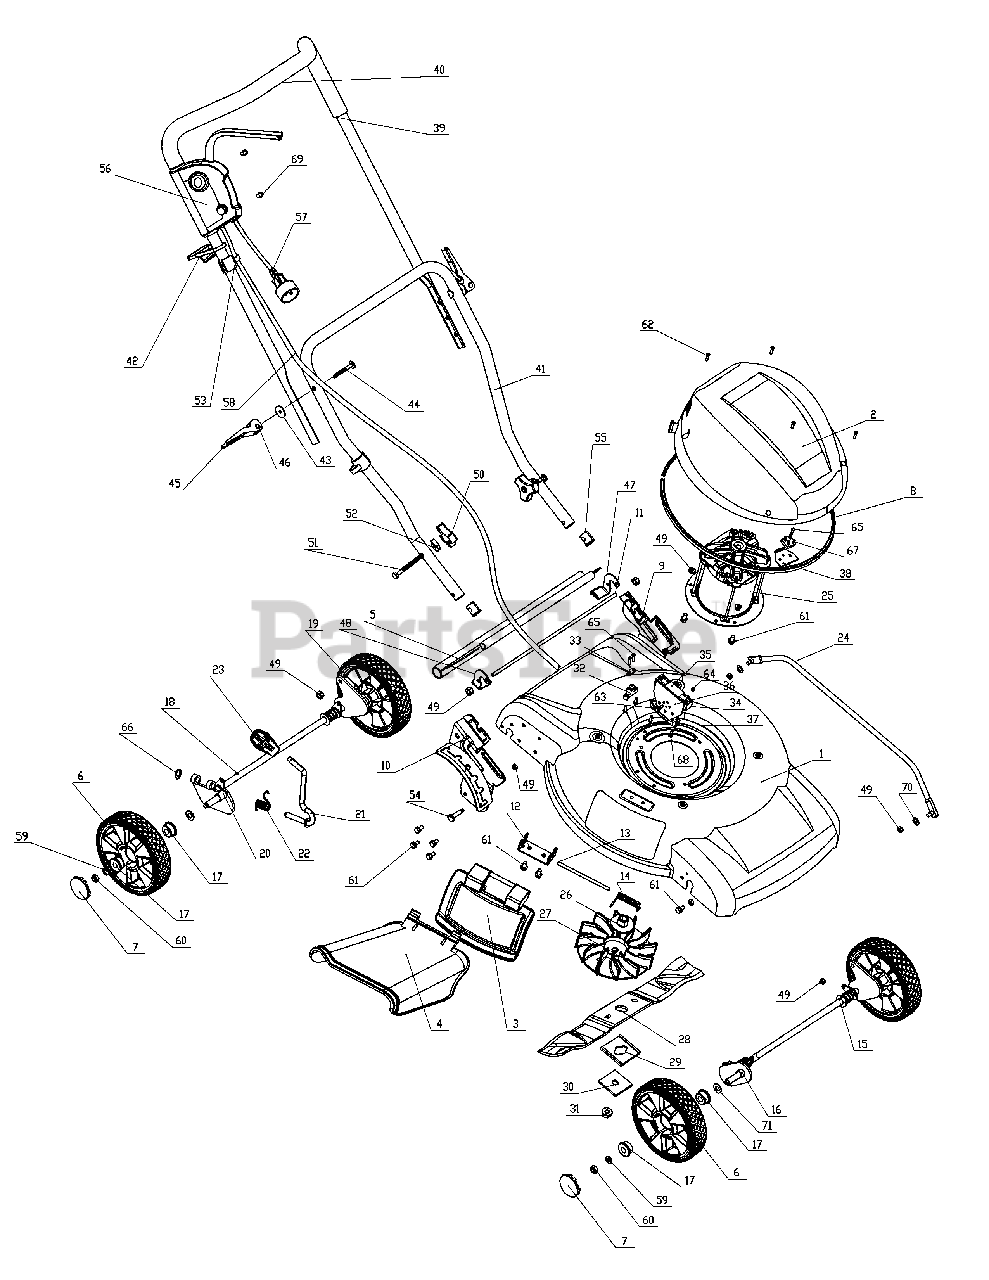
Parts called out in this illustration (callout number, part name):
1	Deck, 19", 3-In-1
2	Shroud
3	Door, Discharge
4	Chute, Discharge
5	Trailshield
6	Wheel, Front
7	Cap, Wheel
8	Seal, Shroud
9	Bracket, Wheel, Left
10	Bracket, Wheel, Right
11	Rod, Trailshield
12	Bracket, Deflector, Chute
13	Rod, Door, Chute
14	Spring, Door, Discharge
15	Axle, Assembly, Front
16	Washer
17	Bush, Wheel
18	Axle, Assembly, Rear
19	Washer
20	Washer
21	Lever, Spring
22	Spring, Lever
23	Knob, Adjustment, Height
24	Link, Height, Adjustment
25	Motor
26	Adapter, Blade
27	Fan, Electric
28	Blade, 19", 2-in-1
29	Washer
30	Washer
31	Nut, M10 x 1.25
32	Support, Cord
33	Keeper, Cord
34	Resistor
35	Resistor, Holder
36	Resistor, Bracket
37	Heat Sink, Resistor
38	Base, Electric-Bridge
39	Handle, Upper
40	Sleeve, Handle, Upper
41	Handle, Lower
42	Retainer, Cord
43	Wash, Flat, 6.6 x 24 x 2
44	Bolt, Black, 50mm
45	Lever, Orange
47	Bracket, Trailshield, Left
48	Bracket, Trailshield, Right
49	Nut, M6
51	Screw, M8
52	Washer, Curve
53	Holder, Cord
55	Cap, Handle
56	Switch Box Assembly
58	Cord, Switch
59	Washer, Flap, 8mm
60	Nut, M8
61	Screw, M6 X 12
62	Screw, M5x12
63	Screw, M4 X 16
64	Nut, Lock, M4
65	Screw, St 4.2 X 16
66	Ring, Snap
67	Electrical, Bridge
68	Screw, St, 4.8 X 16
69	Screw, St, M4.2 X 25
70	Pin, Cotter
71	Washer, Spring
